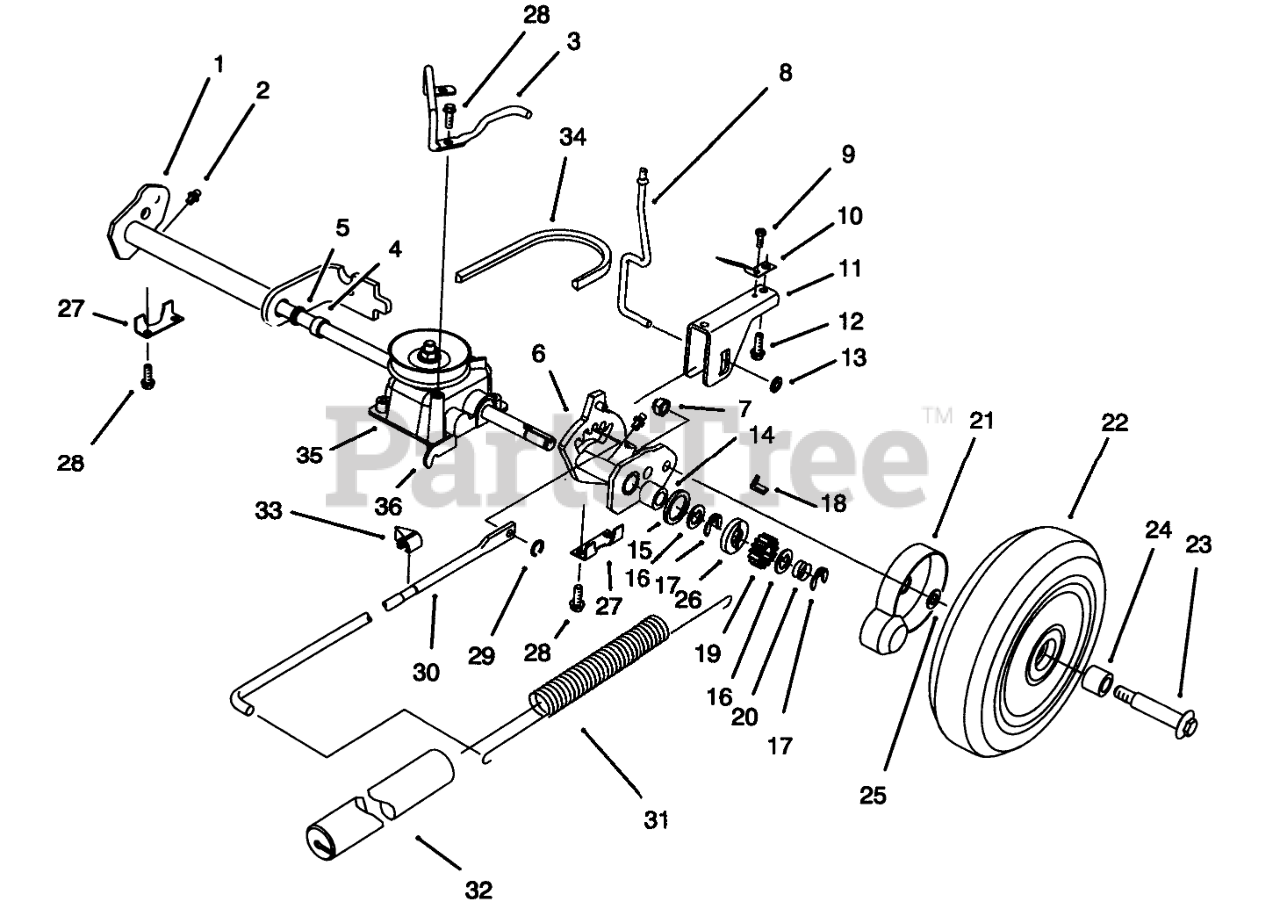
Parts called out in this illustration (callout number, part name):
1	Rear Pivot Assembly R.H.(Incl. Ref. #2, 4, 5 8 14)
2	FITTING-GREASE
3	Retainer Belt
4	BUSHING
5	SEAL-OIL
6	Rear Pivot Assembly L.H. (Incl. Ref. #2, 4, 5 & 14)
7	NUT-HEX
8	TRIGGER ROD
9	SCREW 8 - 32 X 250
10	SPRING - TRIGGER RET
11	SADDLE - HOC
12	SCREW
13	PUSHNUT
14	BEARING-ROLLER
15	RING-FRICTION
16	WASHER-THRUST, KEYED
17	RING-CLIP, LOCKING
18	KEY-ROCKING, LH
19	GEAR-PINION
20	SPRING-COMPRESSION
21	COVER-WHEEL
22	Wheel, Tire & Gear Assy. (Incl. Ref. #24)
23	BOLT-WHEEL
24	BUSHING
25	SPACER-COVER, WHEEL
26	WASHER-CLUTCH
27	REAR SECURING PLATE
28	SCREW-HWH
29	GRIP RING
30	LINK ROD
31	SPRING-COUNTERBALANCE
32	COVER-SPRING
33	INDICATOR-HEIGHT OF CUT
34	V-BELT
35	Gearcase Assembly (Incl. Ref. #36)
36	Bracket-Traction
